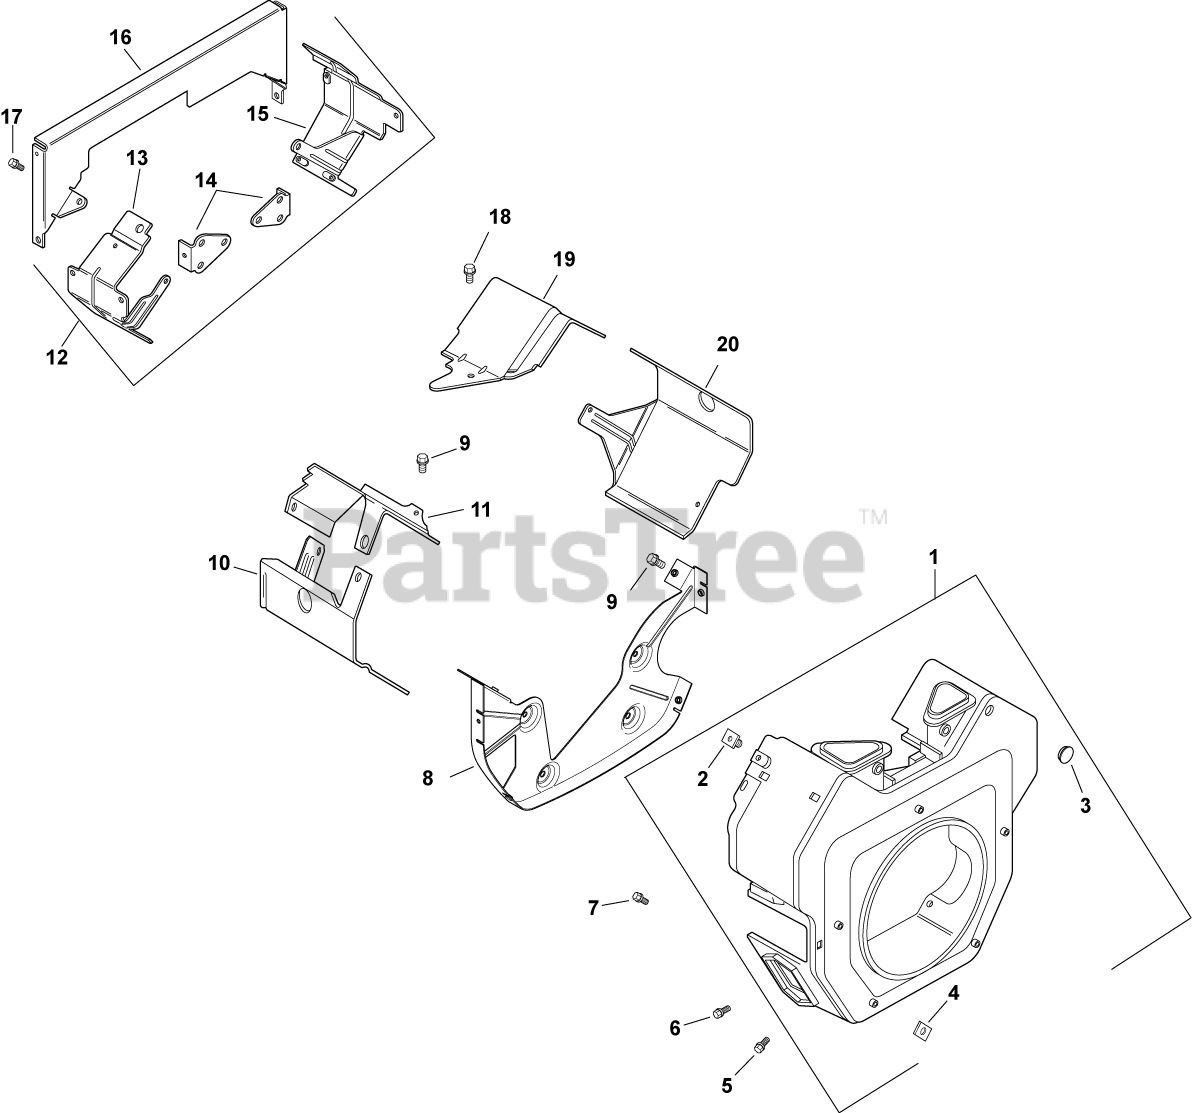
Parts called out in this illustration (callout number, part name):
1	KIT, BLOWER HOUSING ASSEMBLY USE 24 027 477-S
2	NUT, PLASTIC (KM)-USE 25 100 37-S
3	PLUG, BUTTON 9/16
4	NUT, PLASTIC
5	SCREW - USE M-545016-S
6	SCREW,FLG THD FRM M5X0.8X16-(#25086398S)
7	SCREW, FLG THD FRM M5X.8X20-(#25086399S)
8	PLATE, BACKING-USE 24 146 59-S
9	SCREW,FLG THD FRM M6X1.0X16-(#25086397S)
10	KIT, CYL BAFFEL #2 SIDE
11	BAFFLE, VALLEY #2 SIDE-USE 24 063 94-S
12	KIT, "Q"DUCT"
13	BAFFLE, DUCTED AIR-OIL FILTER
15	BAFFLE, DUCTED AIR-STARTER
16	PLATE, BACKING
17	SCREW, FLG M6X1.0X10
18	SCREW, FLG THD FRM M5X.8X10
19	BAFFLE, VALLEY (CH)-USE 24 063 93-S
20	KIT, CYL BAFFEL #1 SIDE
